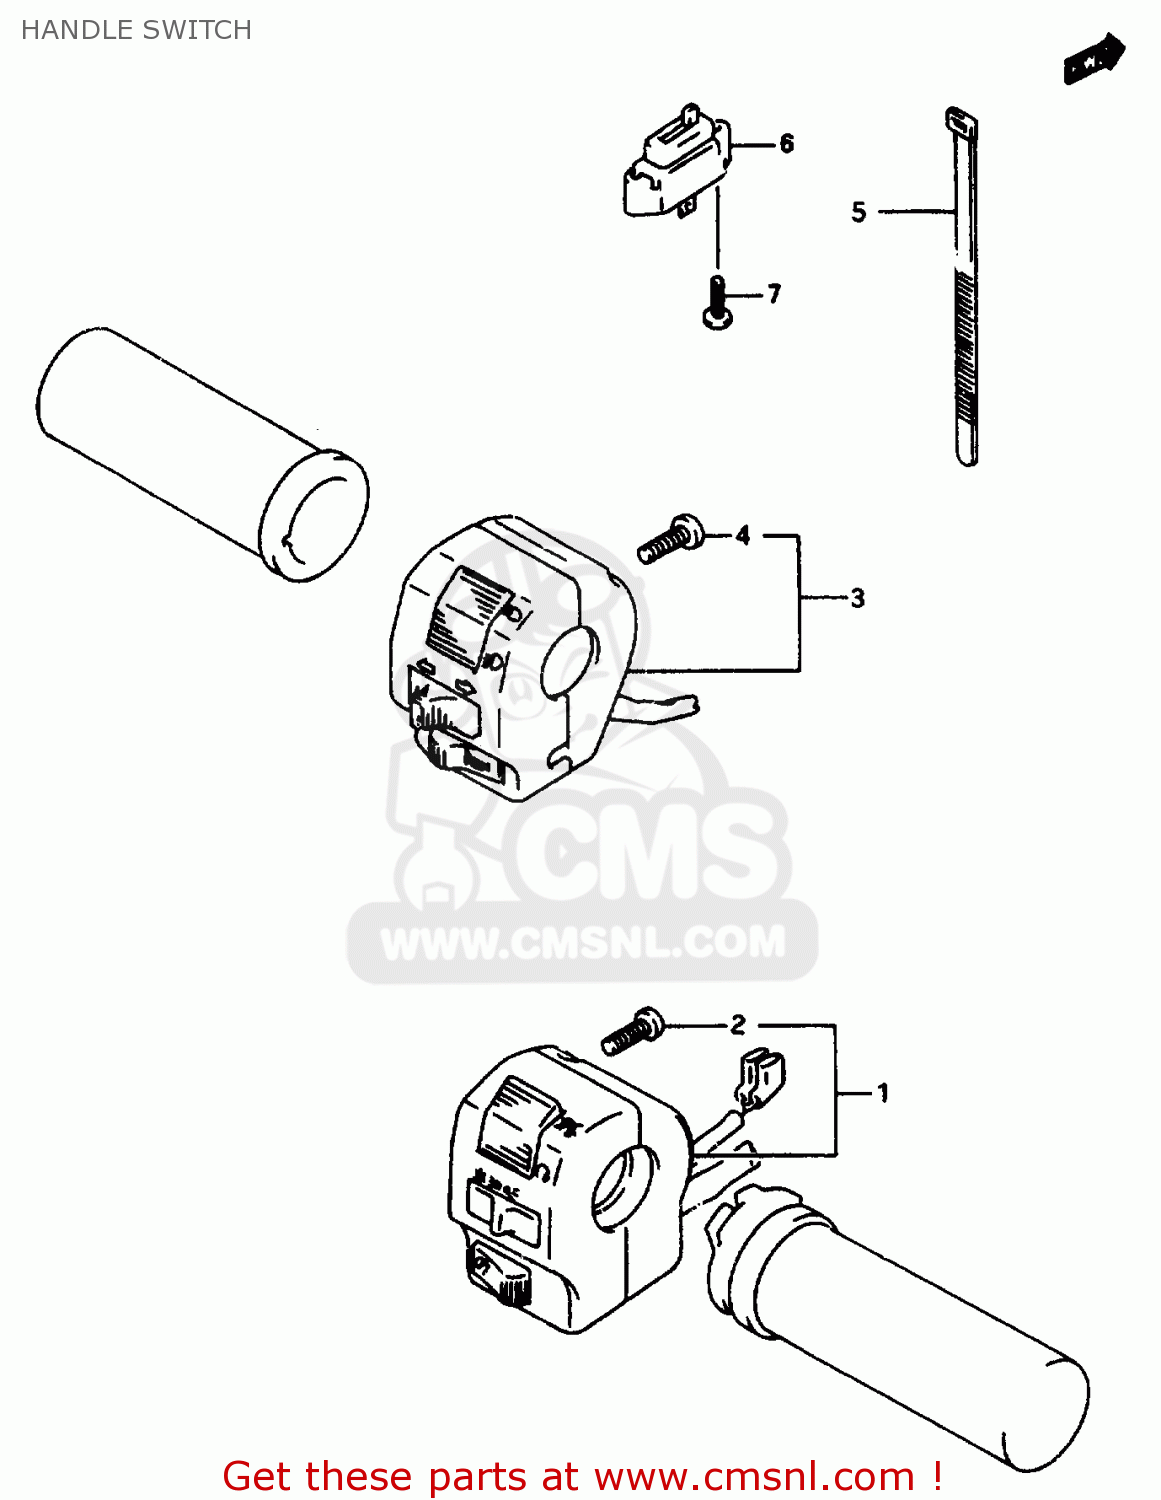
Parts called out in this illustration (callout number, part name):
1	SWITCH ASSY,HANDLE,R
2	SCREW
3	SWITCH,HANDLE,
4	SCREW
5	CLAMP
6	SWITCH ASSY,CLUTCH
7	SCREW
